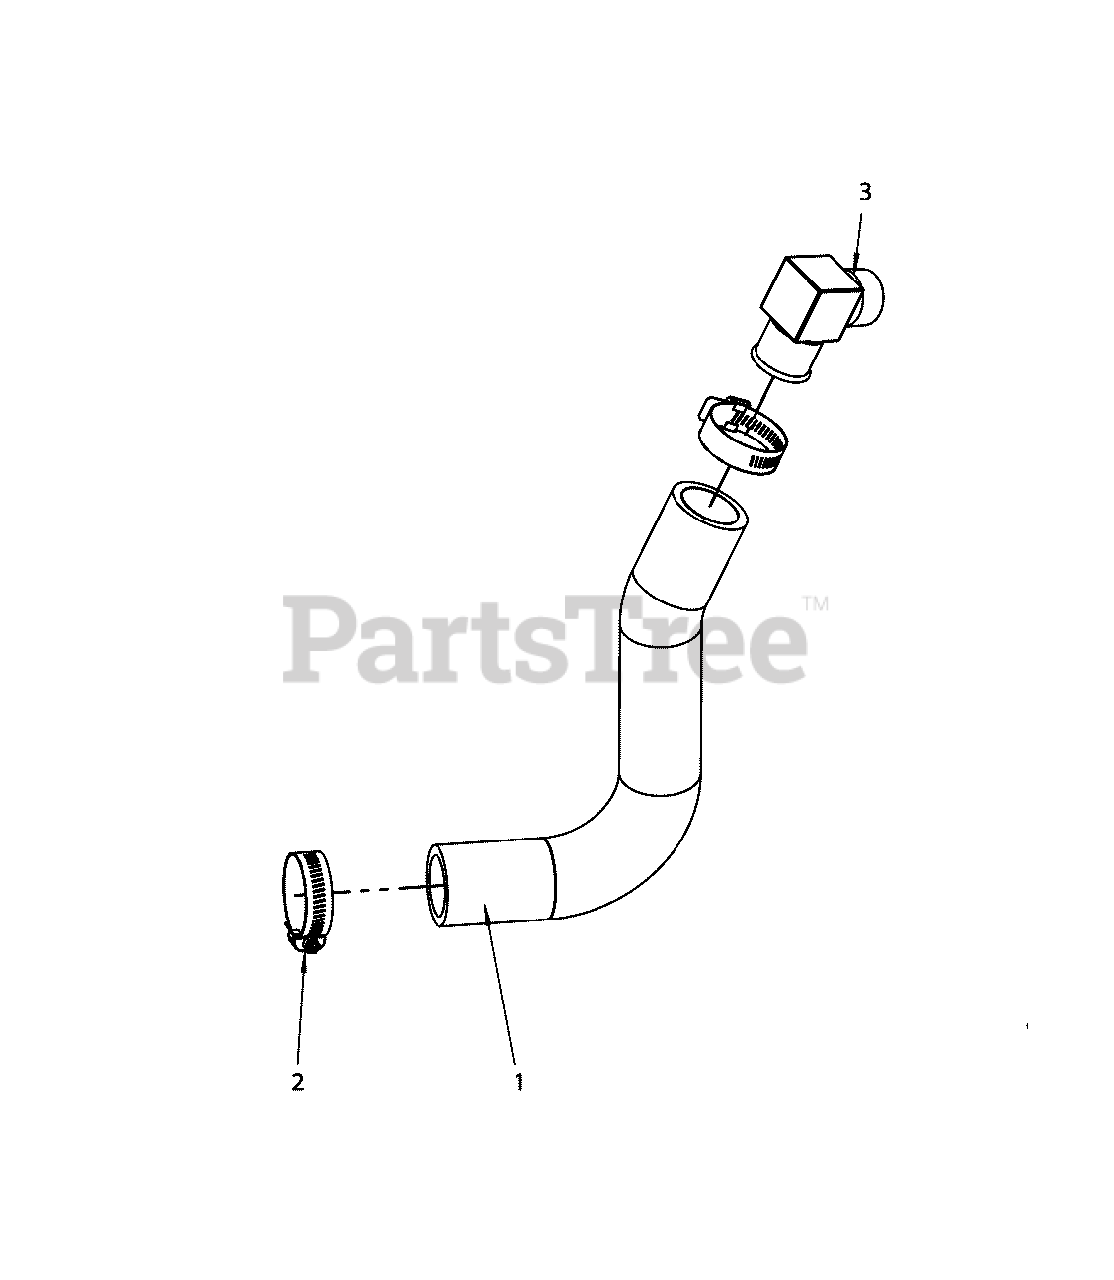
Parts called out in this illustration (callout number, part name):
1	RADIATOR HOSE
2	CLAMP
3	* ELBOW
